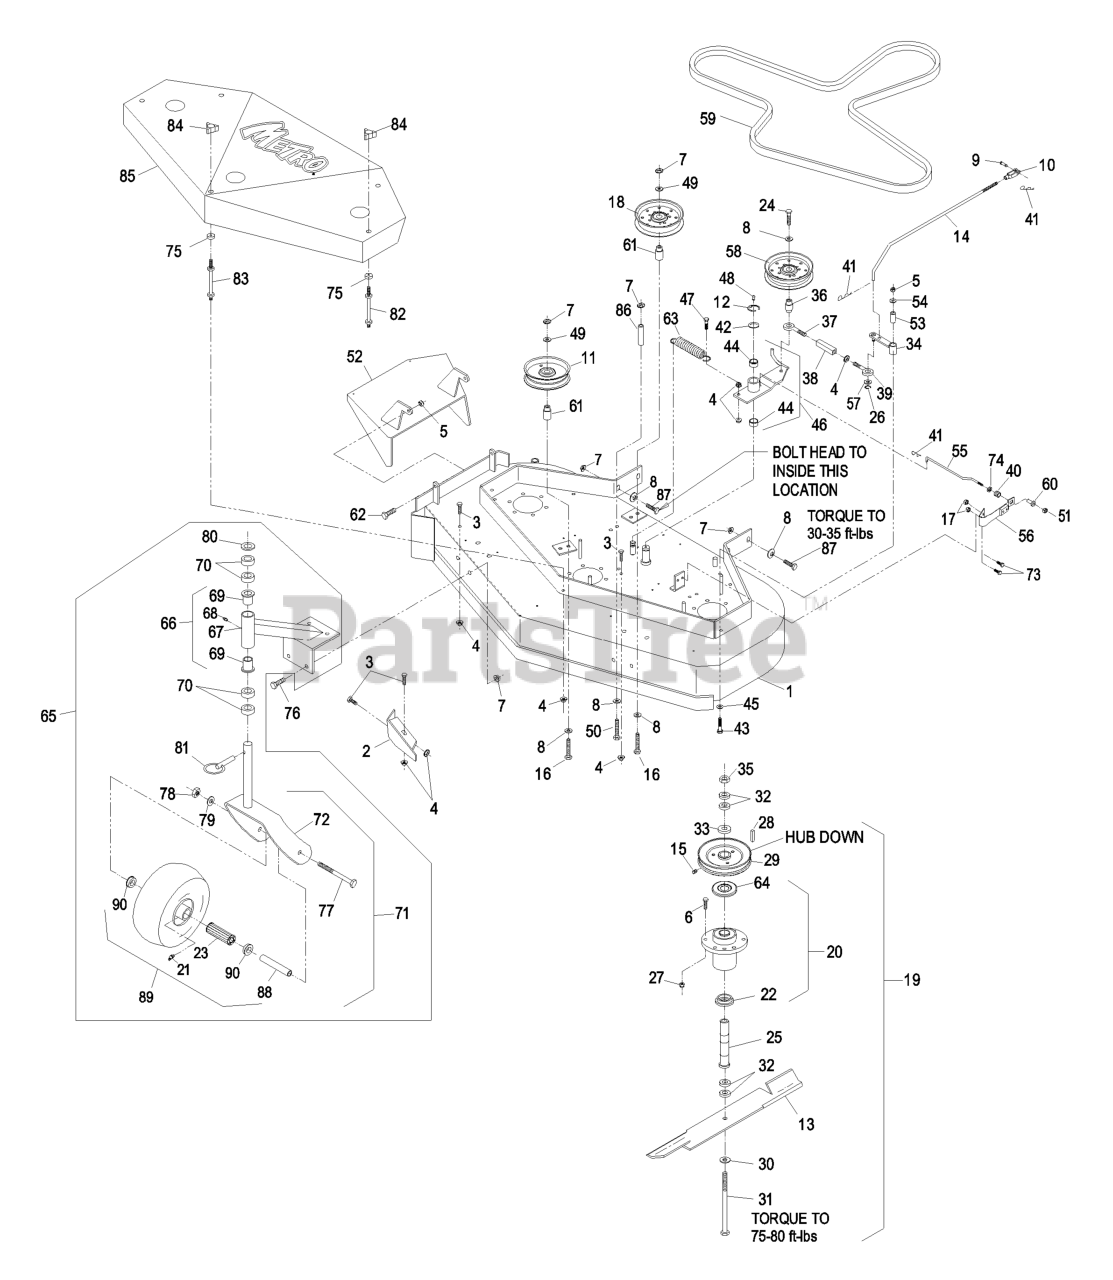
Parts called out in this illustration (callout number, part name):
1	DECK-SERVICE, 48
2	BAFFLE-DOGLEG
3	SCREW-HH
5	NUT-LOCK, NI
6	SCREW-HH
7	NUT-HHF, WHIZ
8	WASHER-BELLEVILLE
9	PIN-CLEVIS
10	YOKE-ADJUSTABLE
11	PULLEY-IDLER
12	RING-RETAINING, EXT
14	ARM-ASSIST, LINKAGE
15	SCREW-SET
16	SCREW-HH
17	NUT-LOCK, NI
19	ASM, CUTTER HOUSING OUTER
20	KIT, CUTTER HOUSING
21	FITTING-GREASE
22	SPACER-GUARD, BOTTOM
23	BEARING
24	SCREW-HH
25	TUBE-SPINDLE, SHORT
26	RING-RETAINING, EXT
27	NUT-LOCK, NI
29	SHEAVE
30	WASHER-SPRING
31	SCREW-CAP, HH
33	WASHER-RETAINER, SHEAVE
34	ARM-ASSIST, 32/36
35	NUT-HEX
36	BUSHING-ENGAGEMENT
37	EYEBOLT-THREAD, LH
38	BODY-TURNBUCKLE
39	EYEBOLT-THREAD, RH
40	SPRING-COMPRESSION
41	PIN-COTTER
42	WASHER-SPINDLE
43	SCREW-HH
44	SLEEVE-BEARING
45	WASHER-SPRING
46	IDLER ARM ASM
47	SCREW-HH
48	FITTING-GREASE
49	WASHER-FLAT
50	SCREW-HH
51	NUT-LOCK, NI
52	WLD,CHUTE 48
53	TUBE-PIVOT
54	WASHER-FLAT
55	ROD-BRAKE
56	PAD AND SPRING ASM
57	WASHER-PLAIN
59	BELT,BLADE 48
60	SPACER-FLANGED
62	SCREW-HH
63	SPRING-EXTENSION
64	GUARD-BEARING, TOP
65	ASM,CASTER/MOUNT
66	SUPPORT ASM
68	FITTING-GREASE
69	BEARING-FLANGED
70	SPACER-CASTER
71	ASM,CASTER/WHEEL
73	SCREW-HH
74	RING-PUSH ON
76	SCREW-HH
77	SCREW-HH
78	NUT-HH
79	WASHER-LOCK
80	WASHER-FLAT
82	STUD-SHIELD, BELT (SHORT)
83	STUD-SHIELD, BELT (LONG)
84	KNOB-3 PRONG
87	SCREW-HH
89	KIT, SP CASTER WHEEL REPL
90	BUSHING
